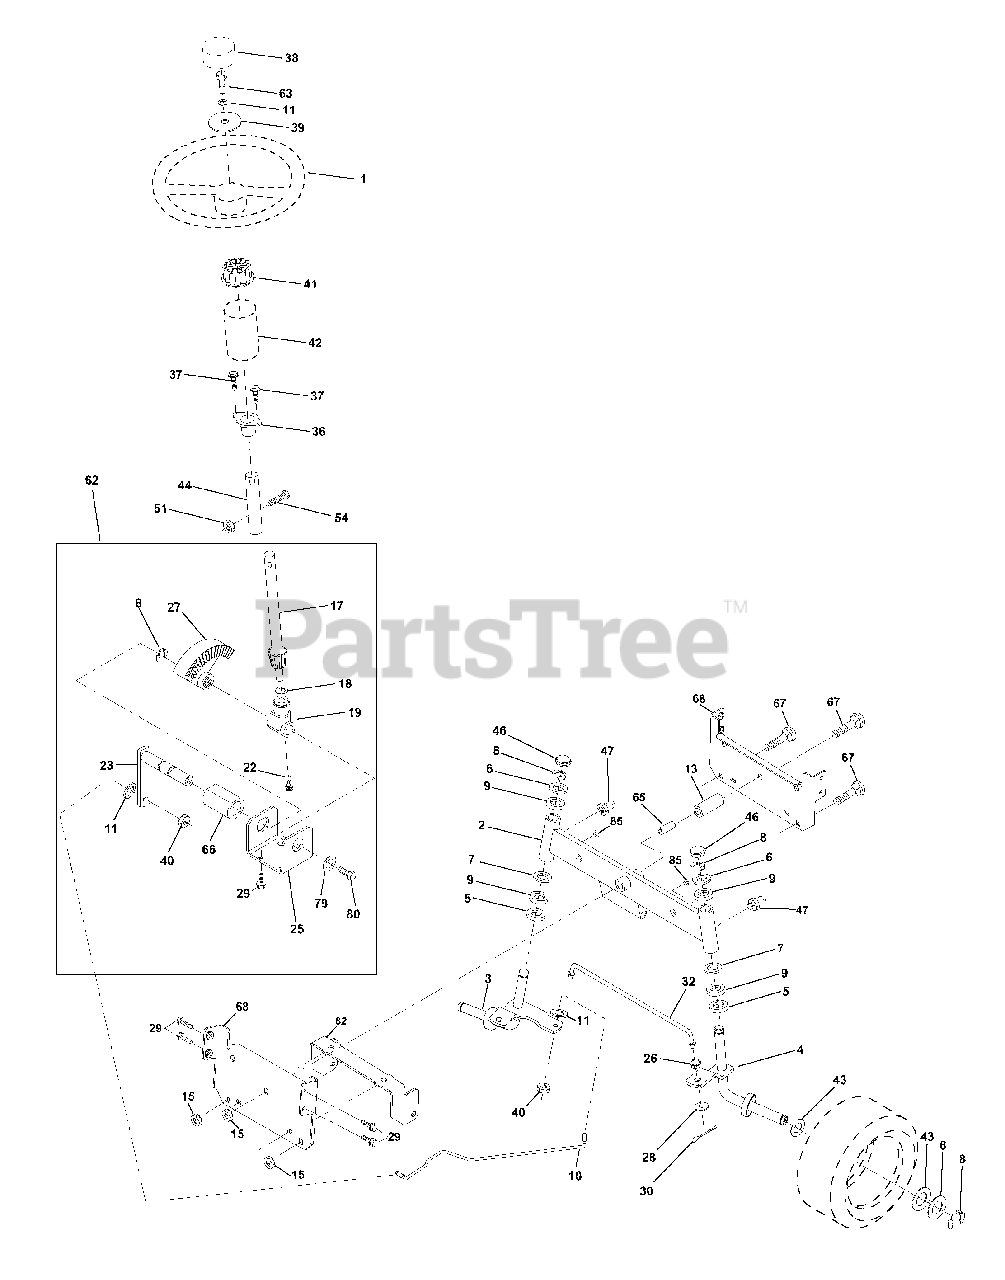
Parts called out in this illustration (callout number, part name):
1	Wheel Steering Auto Black
2	Axle Asm Front
3	Spindle Asm Lh
4	Spindle Asm Rh
5	Bearing Race Thrust Harden
6	Washer 25/32 X 1 5/8 X 16ga
7	Washer 27/32 X 1 1/4 X 16 Ga
8	Ring Klip #t5304-75
9	Bearing Col Strg Blk
10	Link Drag Extended
11	Lockwasher
13	Spacer Bearing Axle Front
15	Hex Flange Lock
17	Shaft Asm Strg 5/8 X 15 19 Lt
18	Washer Thrust 515 x 750 x 033
19	Support Shaft
22	Screw Hex Wsh Hd Torx
23	Shaft Asm Pittman
25	Bracket Steering
26	Bushing Rod Tie Blk Lt
27	Gear Sector
28	Washer 13/32 X 7/8 X 16ga
29	Screw 3/8-16x3/4
30	Pin
32	Rod Tie Wire Form 19 75 Mech
36	Bushing Strg 5/8 Id Dash
37	Screw TT #10-32 x 5 x 3/8 Flange
38	Insert Cap Strg
39	Washer 13/32 x 2-3/8 x 12Ga
40	Locknut Center
41	Adaptor Wheel Strg 640/635 id
42	Boot Dash Steering
43	Washer 25/32 X 1 1/4 X 16 Ga
44	Extension Steering Non-Adjust
46	Cap Spindle Fr Top Blk
47	Fitting Grease
51	Nut Lock Hex W/Ins.
54	Bolt Fin Hex 5/16-18 Unc P
62	Kit Steering Assembly Service
63	Bolt Fin Hex 3/8-16unc x Gr. 5
65	Spacer Brace Axle
66	Bearing Arm Pittman
67	Bolt Rdhd Sq 3/8-16 Unc x 2-3/4
68	Brace Axle
79	Washer 13/32 x 1-1/4 x 12 Ga
80	Bolt Hex Nylon 3/8-16 x 3/4
82	Bracket Susp Chassis Front
85	Fastener Christmas Tree
